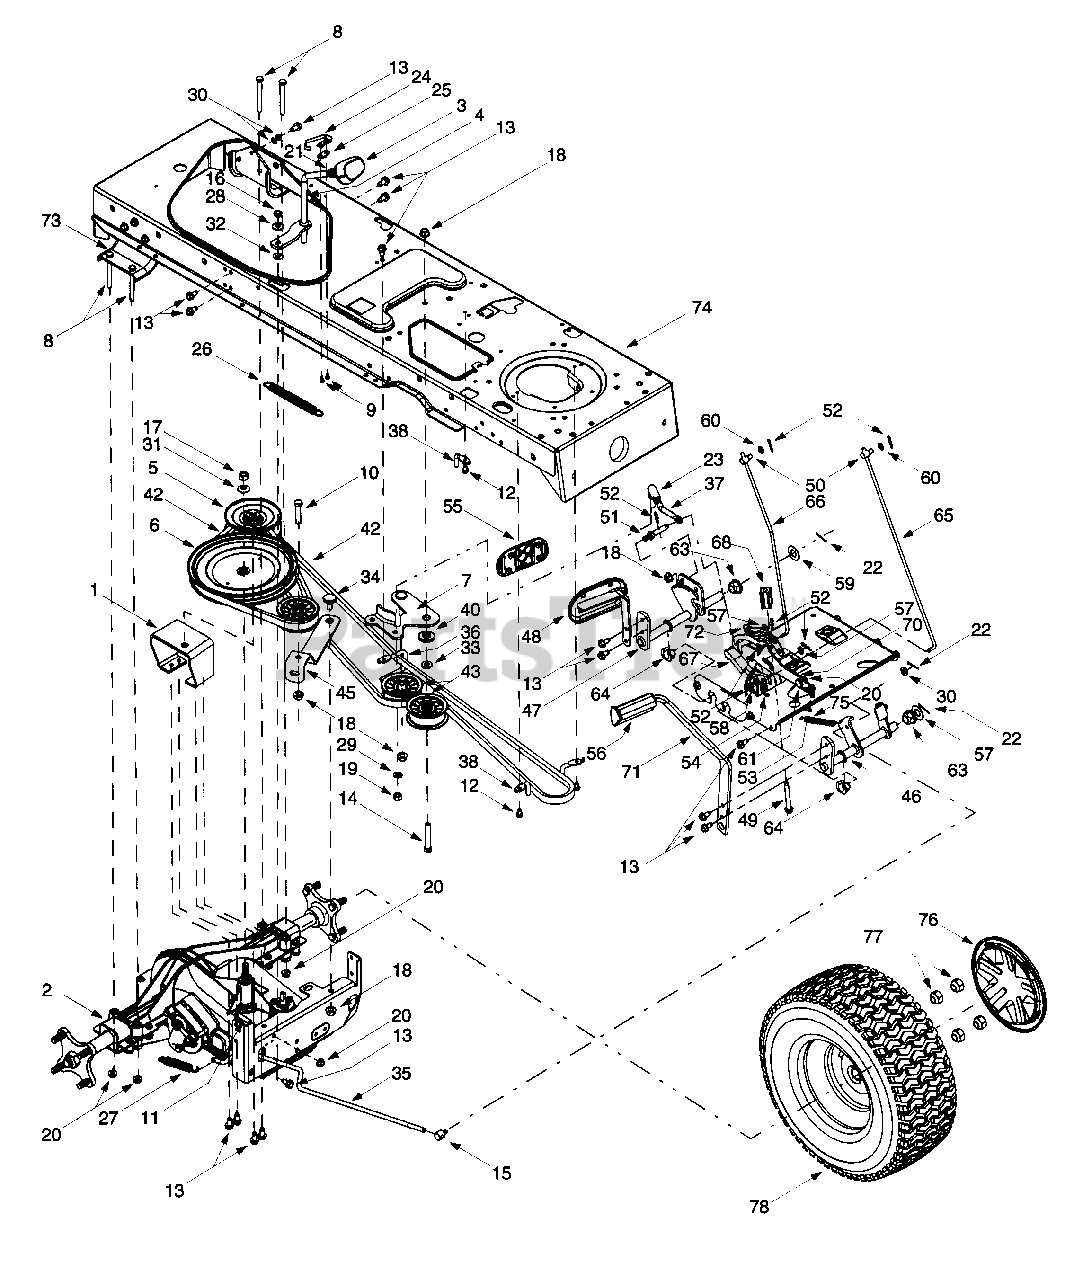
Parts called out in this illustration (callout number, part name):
1	Variable-speed Bracket Assembly
2	Two-speed Transmission Assembly
3	Shifter Knob
4	Shift Lever
5	Variable-speed Pulley Assembly
6	Transmission Pulley, 8.5 x .5 - 36
7	Double-idler Bracket
8	Hex Cap Screw, 5/16-18 x 3
9	Self Tapping Screw, #8-18 x .5
10	Hex Cap Screw, 3/8-16 x 1.75
11	Hex Cap Screw, 5/16-18 x 1.25
12	Self Tapping Screw, 1/4-20 x .5
13	Self Tapping Screw, 5/16-18 x .625
14	Hex Cap Screw, 3/8-16 x 2.25
15	Ferrule, 5/16 x .312 Dia.
16	Hex Jam Nut, 3/8-16
17	Hex Nut, 7/16-20
18	Flange Lock Nut, 3/8-16
19	Hex Nut, 3/8-16
20	Flange Lock Nut, 5/16-18
21	Hex Jam Nut, 3/8-16
22	Cotter Pin
23	Ball Joint, 3/8-24
24	Spring Switch
25	Insulator Nut Plate
26	Extension Spring, .62 Dia. x 6.12
27	Extension Spring, .59 OD x 4.0
28	Bell Washer, .401 x .870 x .063
29	Lock Washer, 3/8
30	Flat Washer, 5/16
31	Bell Washer, .45 x 1.0 x .062
32	Flat Washer, .44 x .75 x .06
33	Flat Washer, .407 x .812 x .135
34	Shoulder Screw, .625 Dia. x .21
35	Brake Rod
36	Belt Guard
37	Idler Adjustment Rod, 3/8
38	Belt Guard Rod
40	Shoulder Spacer, .380 ID
42	Drive Belt, Lower 90.8" Long
42	Drive Belt, Upper 41.5" Long
43	Flat Idler, 2.75 OD
46	Brake Control Shaft Assembly
47	Speed Control Shaft Assembly
48	Auto Drive-Pedal Assembly
49	Self Tapping Screw, 5/16-18 x 2.5
50	Ferrule, 1/4-20
51	Pin, 3/8-16 x 2.43
52	Cotter Pin
53	Compression Spring, .34 OD x 1.0
54	Extension Spring, .5 OD x 1.41
55	Auto Drive-Pedal Pad
56	Brake Pedal Pad
57	Flat Washer, .281 x .5 x .0625
58	Flat Washer, 9/32 x 1/2 x 1/16
59	Flat Washer, .64 x 1.24 x .06
60	Flat Washer, .344 x .062 x .03
61	Shoulder Screw, .437 x 1.62
63	Hex Flange Bearing
64	Split Hex Flange Bearing
65	Cruise Control Rod
66	Brake Lock Control Rod
67	Cruise Latch
68	Spacer, 5/16 x 1.54
70	Auto Drive-Lockout Bracket
76	Hub Cap, Yellow w/Sprig Logo
77	Lug Nut, 7/16-14
